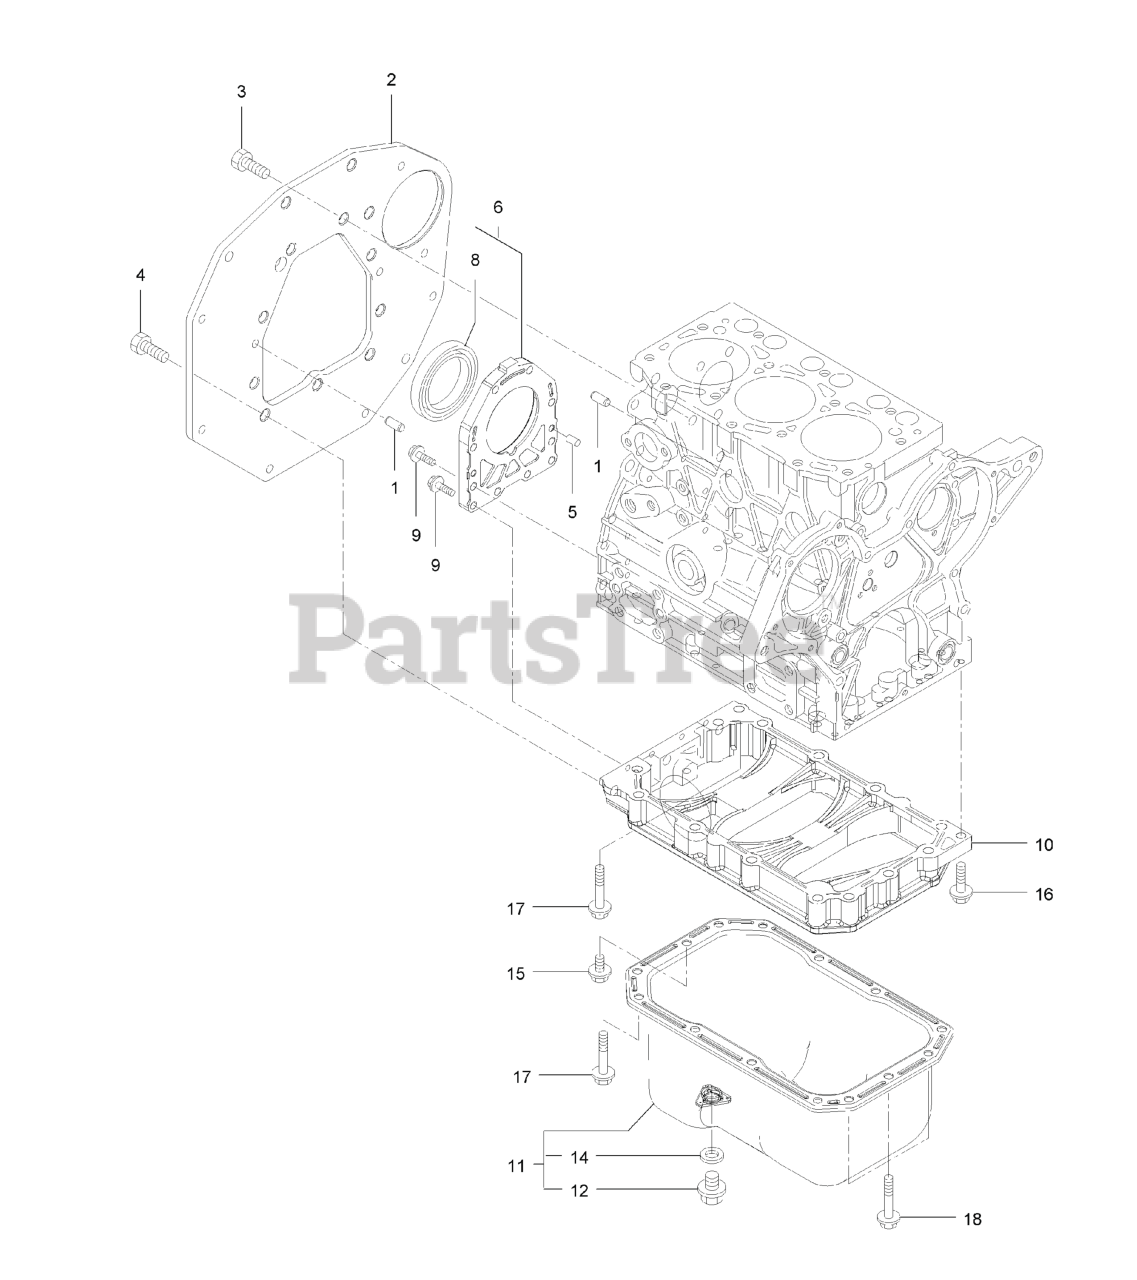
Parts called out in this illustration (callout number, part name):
2	FLANGE-MOUNTING
5	PIN-PARALLEL
6	CASE ASM-OIL SEAL
8	SEAL-OIL
10	SPACER-OIL PAN
11	OIL PAN ASM
14	WASHER-SEAL
